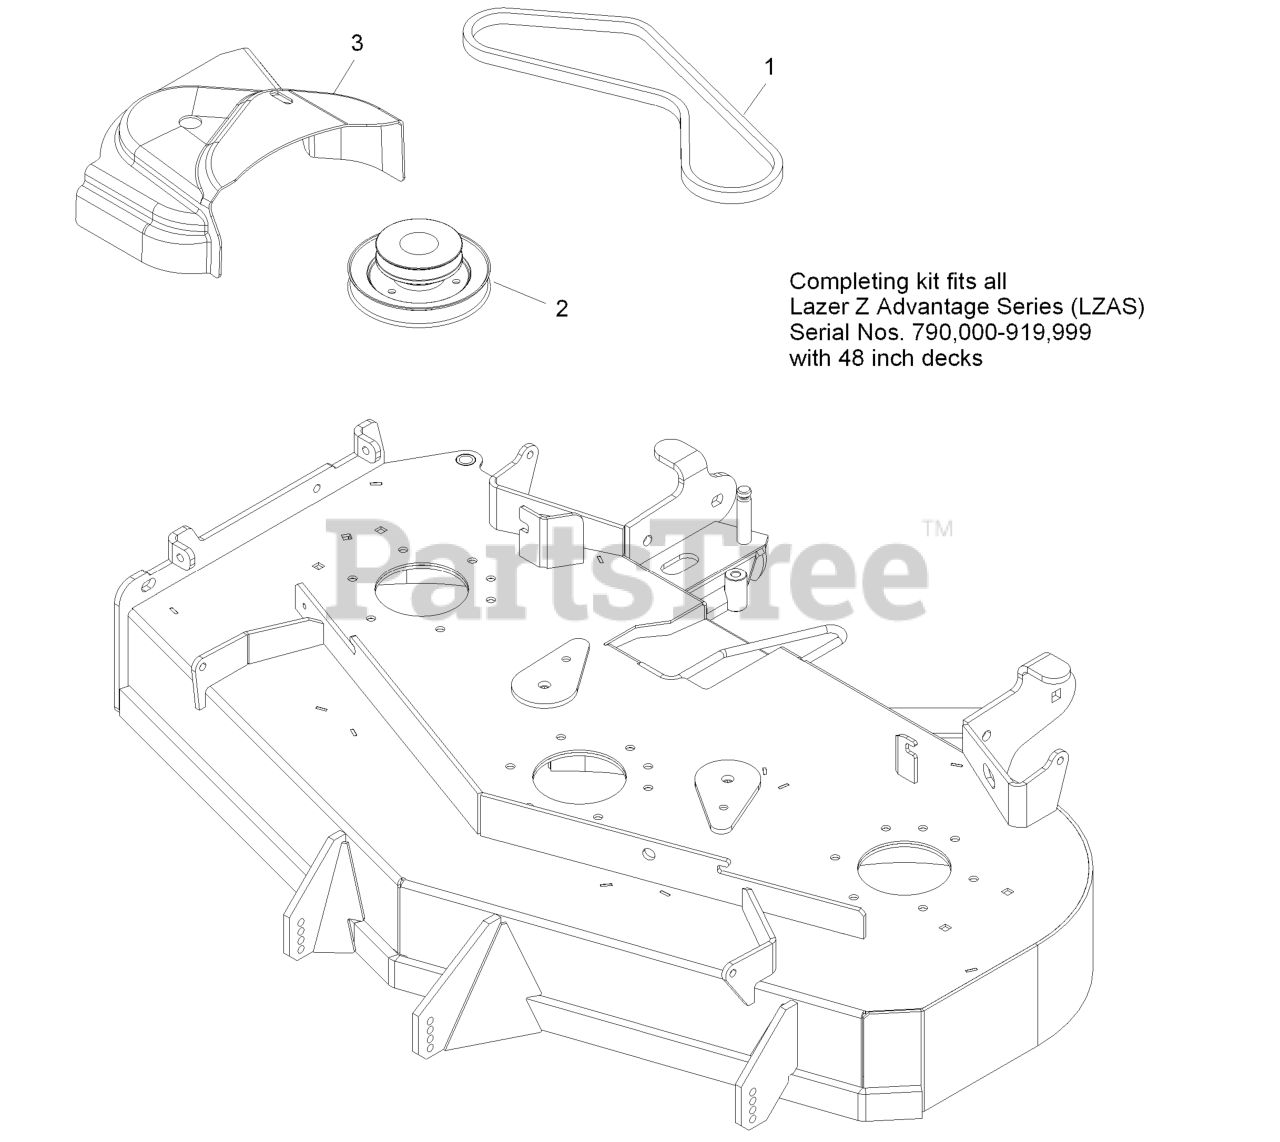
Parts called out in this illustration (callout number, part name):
1	BELT-BLOWER
2	JACKSHAFT,UV DRIVE 484
3	COVER,BELT UV 48
